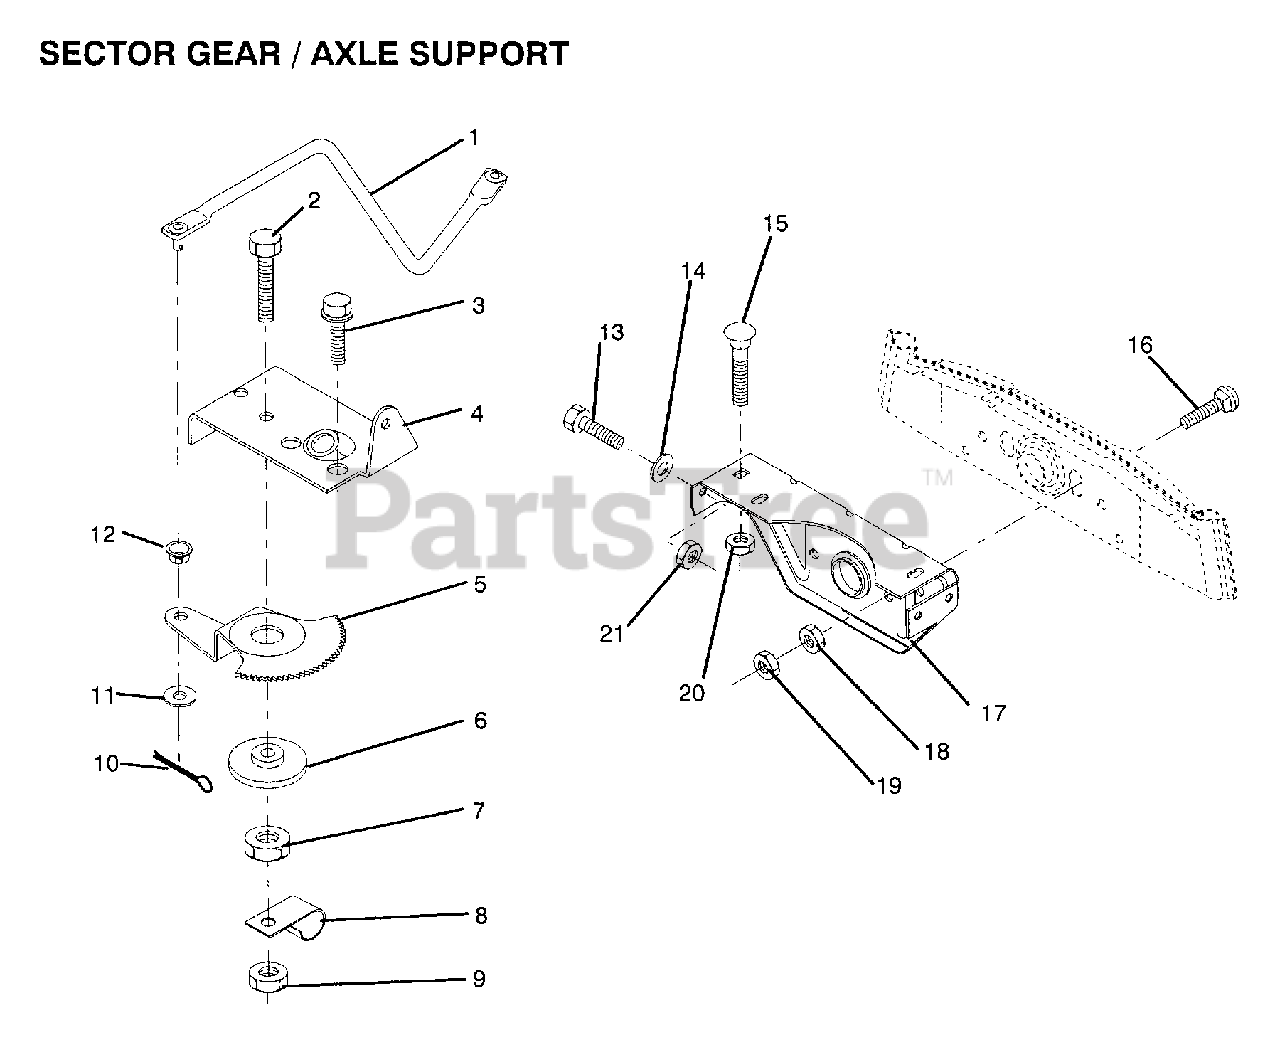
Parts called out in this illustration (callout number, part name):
2	"BOLT,HEX"
3	SCREW LT
4	"PLATE,STR SUPT"
5	GEAR SECTOR
6	BUSHING
7	NUT
8	CLIP INSULATOR
9	NUT LTV
10	COTTER PIN
11	WASHER
12	BUSHING.DRAGLINK
13	BOLT
14	WASHER
15	BOLT
16	BOLT
17	"SUPT,FRT AXLE"
18	NUT.HEX.3/8-16UNC
19	LOCKNUT
